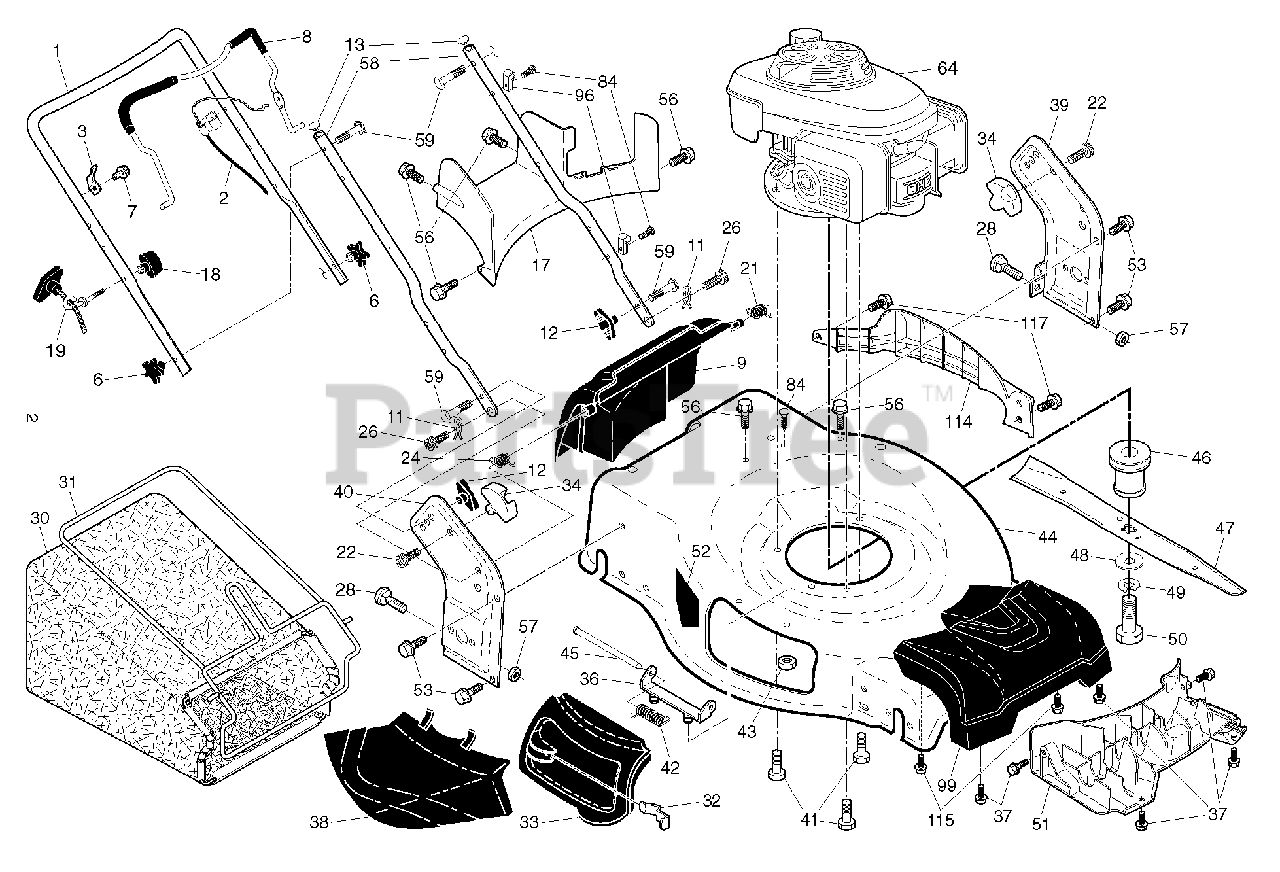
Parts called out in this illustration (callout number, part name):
1	HANDLE.UP.3POS.BS.AW2.GREY
2	CABLE.MZR.50.SNAP-IN
3	BRACKET.UPSTOP.RT
6	KNOB.HANDLE.PLASTIC.STAR.BLACK
8	BAIL.OVER.MOLD.ERGO.MZR.ORANGE
9	DOOR.REAR.ASM.22+.HUSQ.F/RG.CE
11	COTTER.HAIRPIN.DOOR/HANDLE.PIV
12	KNOB, DEFLECTOR
13	PLUG.PLASTIC.7/8".14-20.GAUGE
17	BAFFLE.REAR.22+RGD.AWD.PLASTIC
18	T-KNOB.NEW ROPE GUIDE
19	GUIDE.ROPE.BLK.ZINC.CHROM
21	SPRING.LH.BLACK
22	SCREW.PAN.HEAD.#10
24	SPRING.RH.GRAY
26	SCREW,DOOR/HANDLE.PIVOT
28	BOLT.CARRIAGE.LN.5/16-18X.5/8
30	GBAG.BA85028EM.NOFRAME.GRY/SLV
31	FRAME.GBAG.22+.BLK
32	LATCH.DOOR.ZINC
33	DOOR.MULCH.22 PLUS.HUSQ.GREY
34	BRACKET.GRASSBAG.ATTACHING.BLK
36	BRACKET.ASM.HINGE.21.FWGD.
37	SCREW.HI-LO. 5/16 X 1.00
38	DEFLECTOR.CLIPPING.22.BLACK
39	BRACKET.ASM.HANDLE.LT.22+.GREY
40	BRACKET.ASM.HANDLE.RT.22+.GREY
41	BOLT 3/8-16X1-1/8
42	SPRING.TORSION
43	NUT.HEX.FLANGE.1/4
44	HOUSING.22+AWD.MC.WO.HD.CE.ORG
45	ROD.HINGE.21
46	ADAPTER.BLADE.25MM.3MPH
47	BLADE.22+4N1.2PIN.5STAR.(P07)
48	WASHER,HARDEN
49	LOCKWASHER
50	SCREW, HEX HD 3/8-24 X 1-3/8
51	BAFFLE.FRONT.22+PLASTIC.(2 2)
52	DECAL.INTERNATIONL.CUTFINGER
53	BOLT.5/16HEX.WHS.HD
56	SCREW.HX.13X.750
57	NUT.FLANGE.5/16
58	HANDLE.LOWER.22+.BT.GRAY
59	BOLT, HANDLE 5/16-18X1.75
84	FASTENER.PUSH.O.250X0.783
96	CLIP.CABLE.BLK
99	COVER.ASM.FRONT.SHROUD.HUS.AWD
114	RP BUMPER.HUSQVARNA
115	SCREW.SHOULDER.5/16X1.375
117	BOLT.HEX.HD.WASHER.5/16-18X.75
